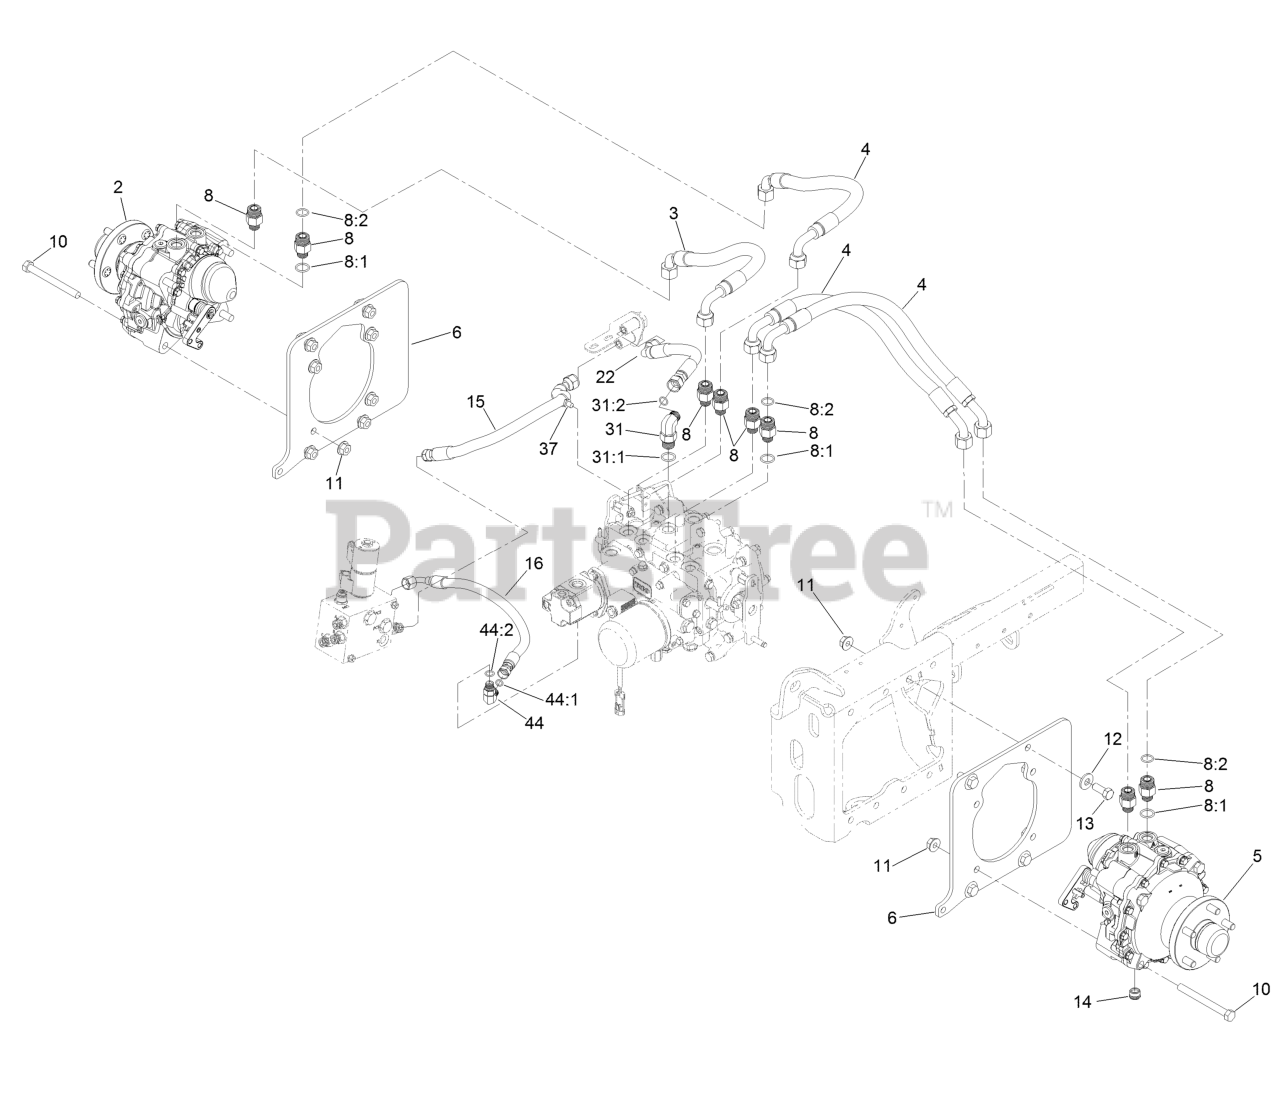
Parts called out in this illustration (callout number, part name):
2	Motor-HYD, RH
3	Hose ASM
4	Hose ASM
5	Motor-HYD, LH
6	Plate-Motor
8	Fitting-Straight
8:1	O-Ring
10	Screw-HH
11	Nut-HHF
12	Washer-Spring
13	Screw-HH
14	Plug-Magnetic
15	Hose ASM
16	Hose ASM
22	Hose ASM
31	Fitting-Elbow, 90 DEG
31:1	O-Ring
31:2	O-Ring
37	Clip-Tie
44	Fitting-Elbow, 90 DEG
44:1	O-Ring
44:2	O-Ring
